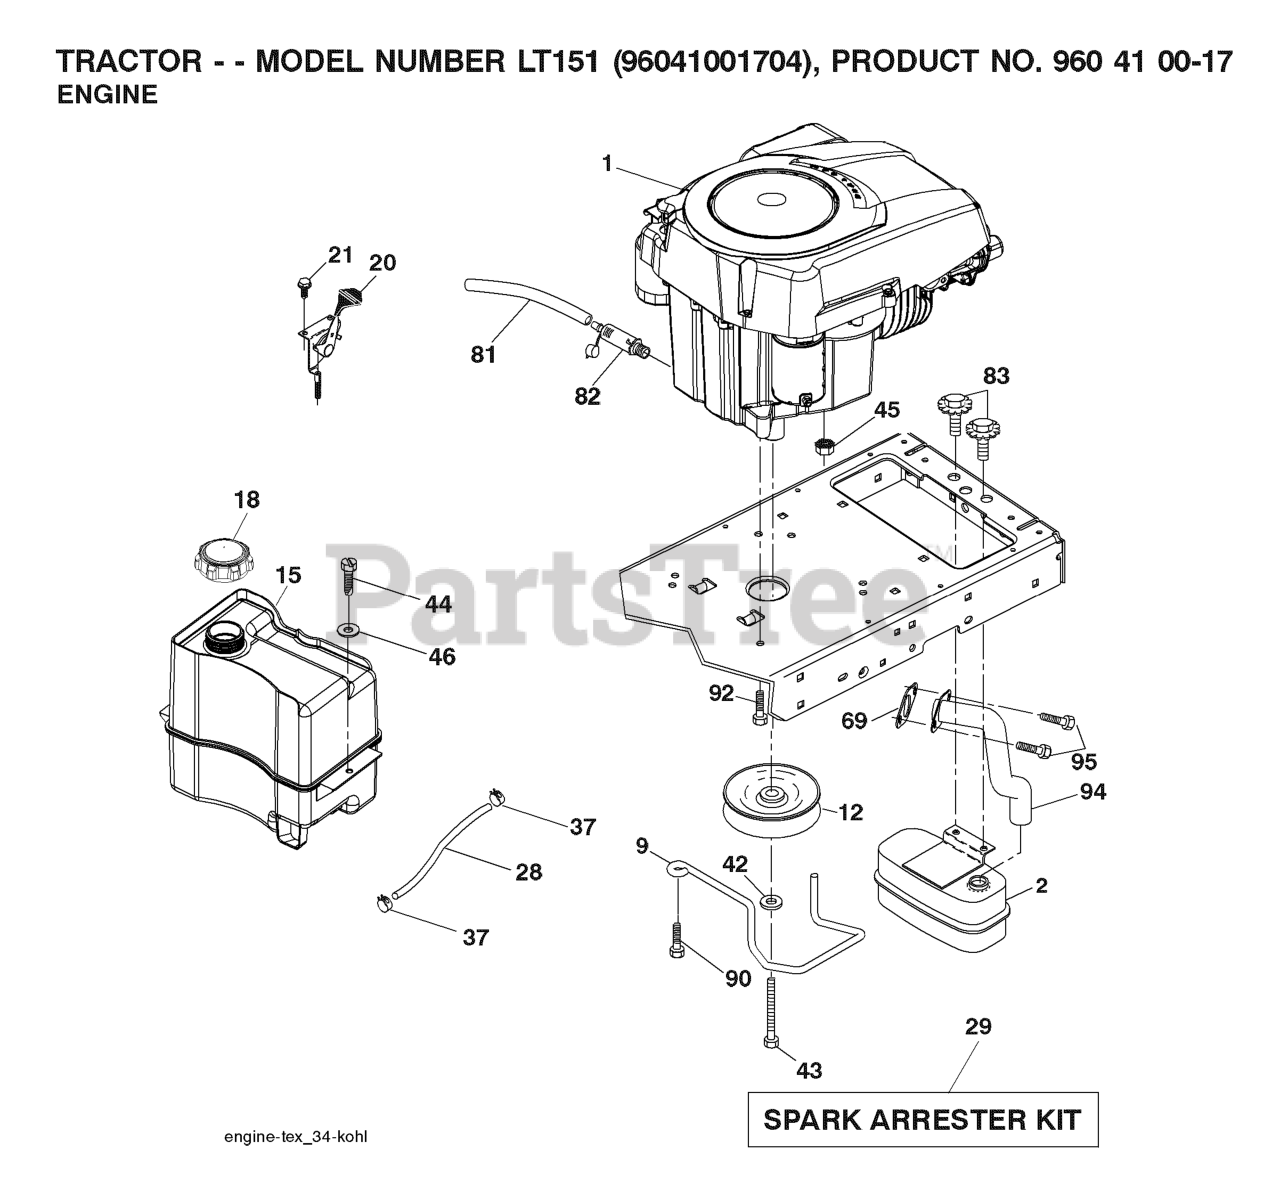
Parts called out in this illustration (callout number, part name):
2	MUFFLER.SINGLE.CYL.KOHL/B&S
9	KEEPER.BELT.ENGINE.3.25 (3 2)
12	PULLEY ENGINE
15	RP TANK FUEL FRT 1.5 GAL
18	FUEL CAP
20	CONTROL.TH/CK.C.
21	SCREW
28	LINE.FUEL.20
29	KIT.SPARK ARRESTOR 794945 B&S
37	HOSE CLAMP
41	LOCKWASHER
43	BOLT HEX 7/16-20X4-1/4"
44	SCREW HEXWSHR 1/4-20X3/4
45	NUT
69	GASKET.EXHAUST.KOHLER
81	TUBE, DRAIN OIL ASM.
82	PLUG DRAIN OIL EASY
83	BOLT.5/16-18UNCX3/4 W/SEMS.BLK
90	SCREW 3/8-16X1
92	SCREW 3/8-16X1
94	RP.TUBE.EXHAUST.KOHL.COURAGE
95	SCREW.SOCKET HD.5/16-1
